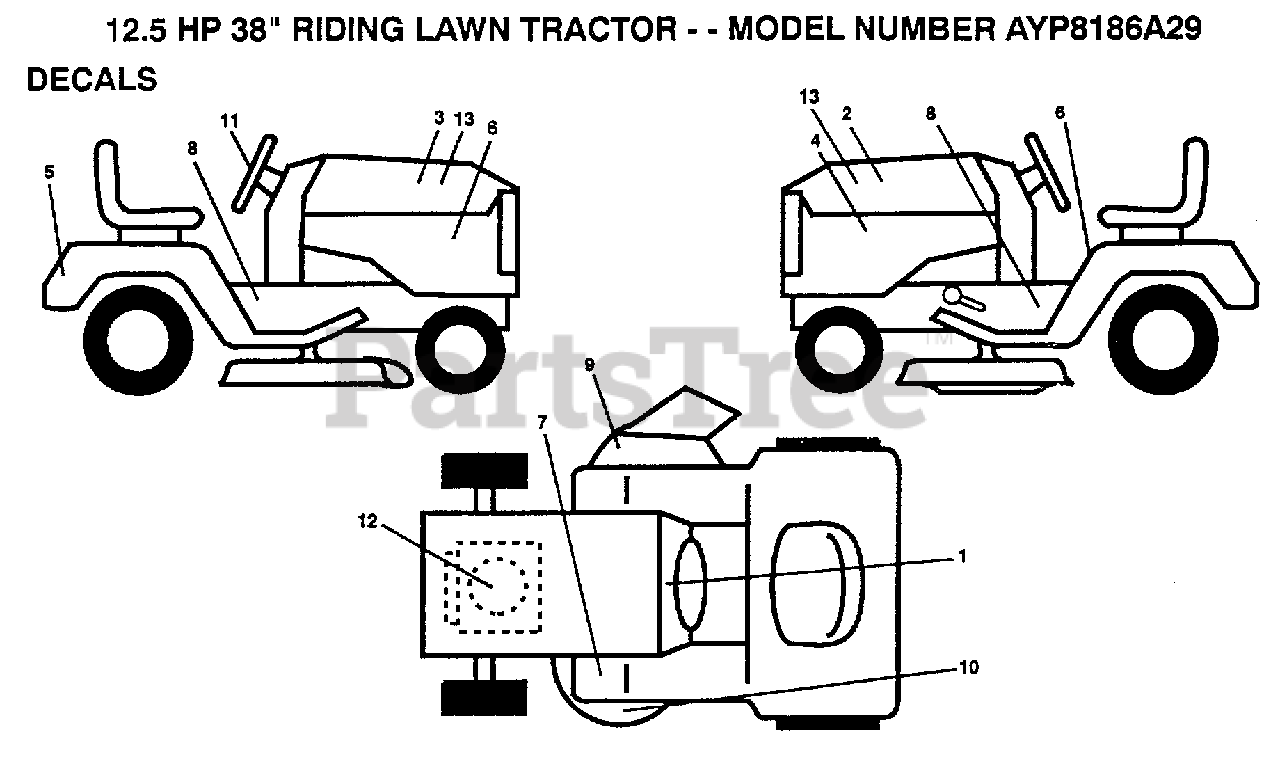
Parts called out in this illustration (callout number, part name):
4	DECAL, PANEL SIDE
6	DECAL
8	DECAL, CHASSIS
9	DECAL WARING
10	DECAL INSTRUCTION CAUTION
12	DECAL.ENG.272559
